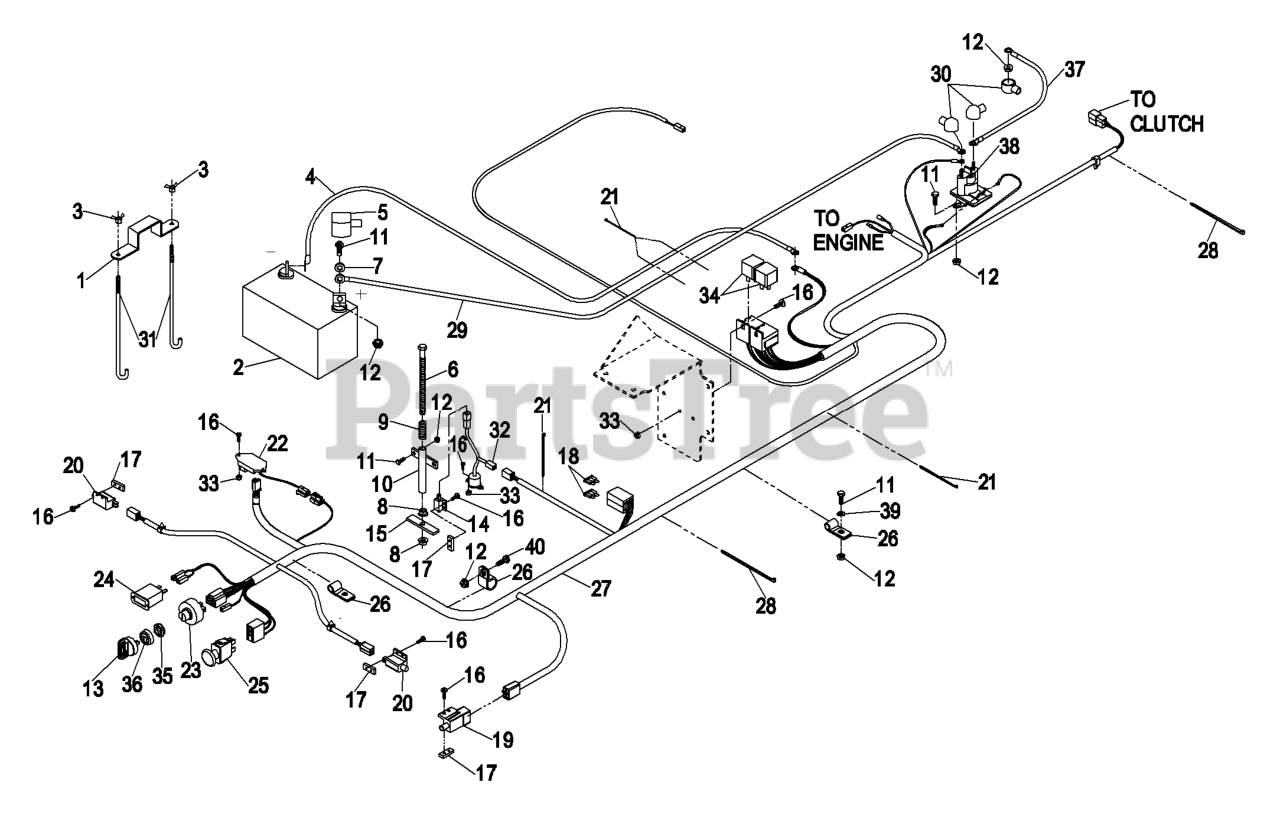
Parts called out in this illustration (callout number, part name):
3	WINGNUT
4	WIRE-GROUND
6	SCREW-HH
7	WASHER-FLAT
9	SPRING-SWITCH, SEAT
11	SCREW-HH
13	KEY-IGNITION
14	SWITCH-CLOSED, NORMALLY
15	PLATE-SWITCH, SEAT
16	SCREW-PPH
17	PLATE-TAPPED
18	FUSE-BLADE TYPE, 20 AMP
20	SWITCH-OPEN, NORMALLY
21	TIE-CABLE
22	MODULE-DELAY, SEAT
24	METER-HOUR
26	CLIP-LOOM
27	HARNESS,WIRING KA
28	TIE-PLASTIC
30	INSULATOR-SOLENOID
31	BOLT-HOLDDOWN
33	NUT-LOCK, NI
35	NUT-SWITCH, IGNITION
36	SEAL-SWITCH, IGNITION
39	WASHER-FLAT
40	SCREW-HH
